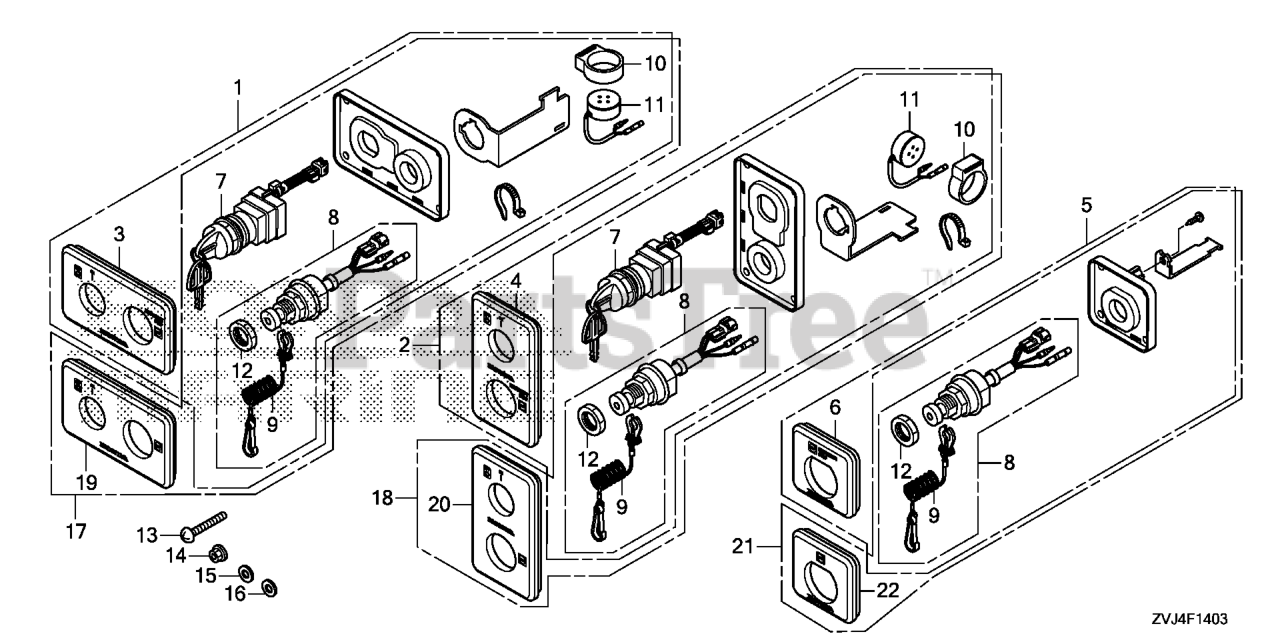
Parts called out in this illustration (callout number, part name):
1	PANEL ASSY., KEY SWITCH
2	PANEL ASSY., KEY SWITCH
3	PANEL, KEY SWITCH
4	PANEL, KEY SWITCH
5	PANEL ASSY., EMERGENCY STOP
6	PANEL, EMERGENCY STOP SWITCH
7	SWITCH ASSY., COMBINATION
8	SWITCH ASSY., EMERGENCY STOP
9	WIRE, EMERGENCY
10	SUSPENSION, AUDIBLE PILOT
11	BUZZER, WARNING
13	SCREW, PAN (5X40) DUAL QTY = (8) (SINGLE)
14	NUT, FLANGE (5MM)
15	WASHER, PLAIN (5MM)
16	WASHER, SPRING (5MM)
17	PANEL ASSY., KEY SWITCH
18	PANEL ASSY., KEY SWITCH
19	PANEL, KEY SWITCH
20	PANEL, KEY SWITCH
21	PANEL ASSY., EMERGENCY STOP
22	PANEL, EMERGENCY STOP SWITCH
